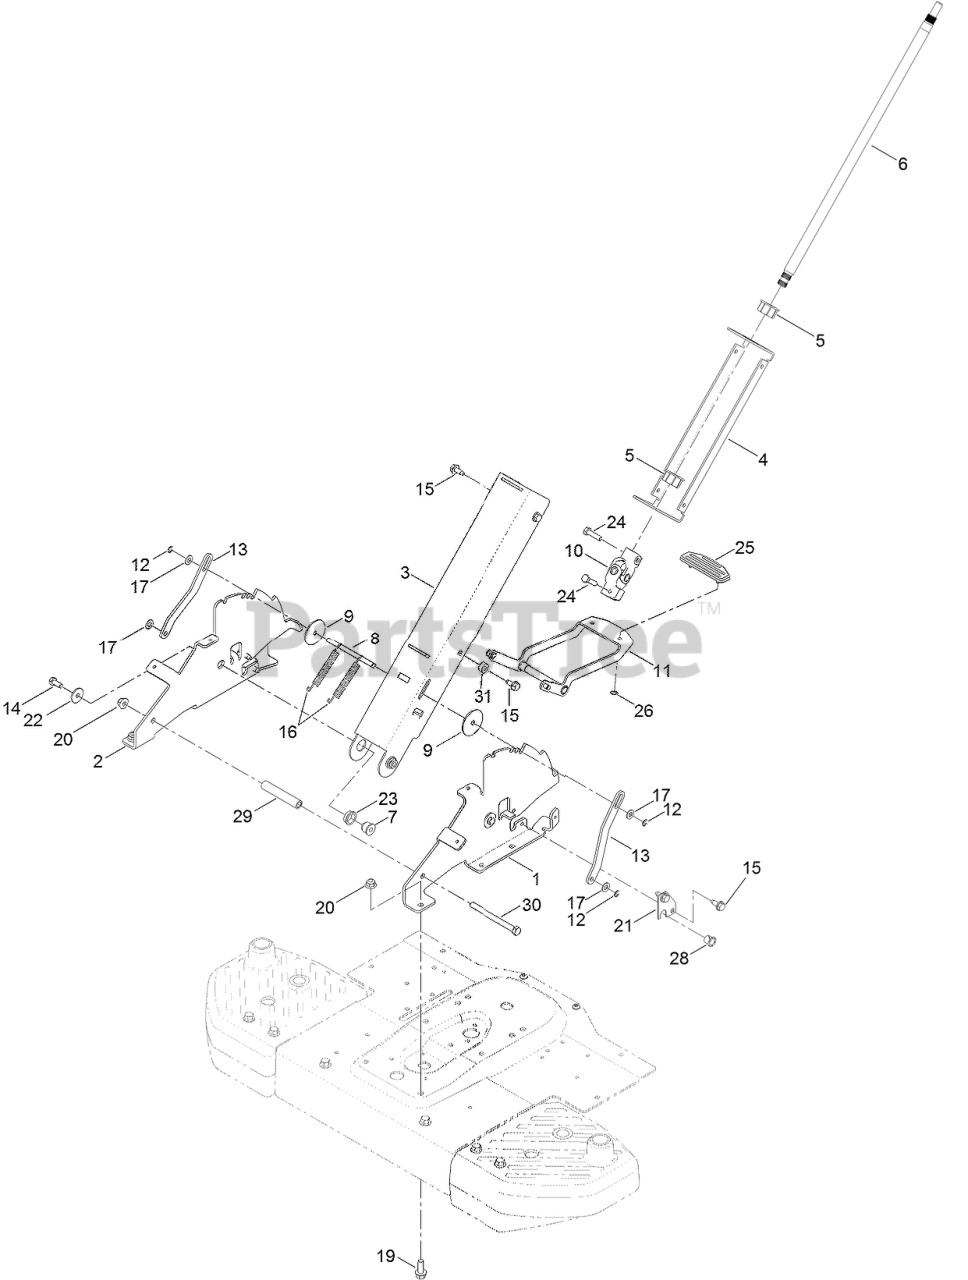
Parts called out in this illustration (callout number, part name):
1	BRACKET-PIVOT, COLUMN (LH)
2	BRACKET-PIVOT, COLUMN (RH)
3	COLUMN-FRONT
4	COLUMN-BACK
5	BUSHING-STEERING, UPPER
6	SHAFT-STEERING, UPPER
7	SPACER-PIVOT, COLUMN
8	ROD-PLUNGER
9	WASHER-SHAFT, TILT
10	U-JOINT ASM
11	RELEASE PEDAL ASM
12	E-RING
13	PLATE-PLUNGER
14	SCREW-HH
15	SCREW-HWHTF
16	SPRING-EXTENSION
17	WASHER-PLAIN
19	SCREW-HHF
20	NUT-HF, NI
21	PLATE-RETAINER
22	WASHER-PIVOT
23	BUSHING-FLANGE
24	SCREW-HH
25	PAD-TILT PEDAL
26	NUT-PUSH
28	BUSHING-NYLINER
29	SPACER
30	SCREW-HH
31	SPACER
